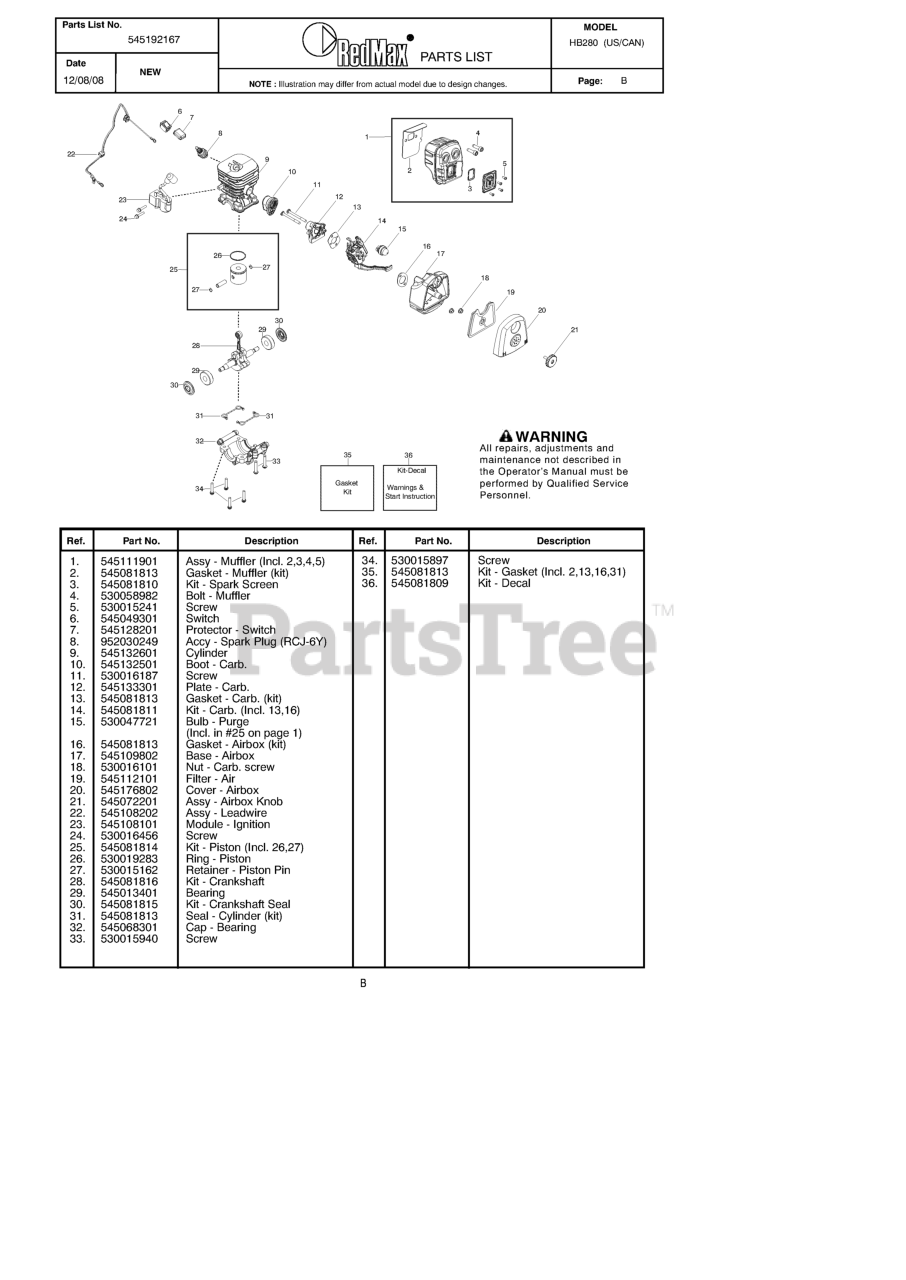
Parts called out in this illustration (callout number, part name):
1	ASS - MUFFLER (2,3,4,5)
2	GASKET - MUFFLER (kit)
3	KIT - SPARK SCREEN
4	BOLT - MUFFLER
7	PROTECTOR - SWITCH
8	ACCY - SPARK PLUG (RCJ-6Y)
9	CYLINDER
10	BOOT - CARB
12	PLATE - CARB
13	GASKET - MUFFLER (kit)
14	KIT - CARB (13,16)
15	BULB - PRIMER
16	GASKET - MUFFLER (kit)
17	BASE - AIR BOX
18	NUT - CARB SCREW
19	FILTER - AIR
20	COVER - AIR BOX
21	ASSY - AIR BOX KNOB
22	ASSY - LEAD WIRE
23	MODULE - IGNITION
25	KIT - PISTON (26,27)
26	RING - PISTON
27	RETAINER - PISTON PIN
28	KIT - CRANKSHAFT
30	KIT - CRANKSHAFT SEAL
31	GASKET - MUFFLER (kit)
32	CAP - BEARING
35	GASKET - MUFFLER (kit)
36	KIT - DECAL
